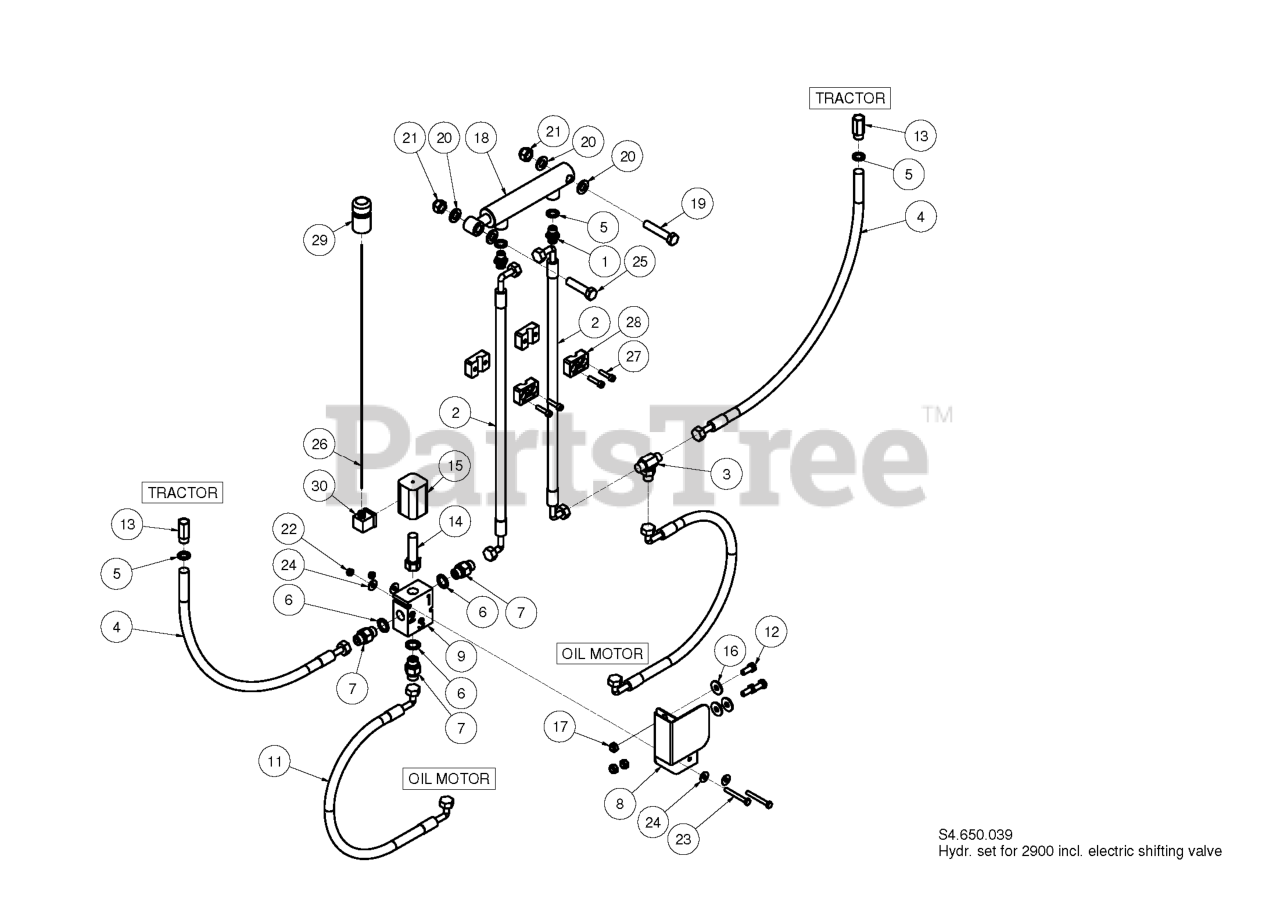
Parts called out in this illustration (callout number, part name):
2	HYDRAULIC HOSE
3	CONNECTION T-3/8"
4	HYDRAULIC HOSE
9	VALVE HOUSING
11	HYDRAULIC HOSE
17	LOCKNUT M8
18	HYDRAULIC CYLINDER
20	COVER WASHER
22	LOCKNUT M6
24	WASHER - 26X6.5X1.6
